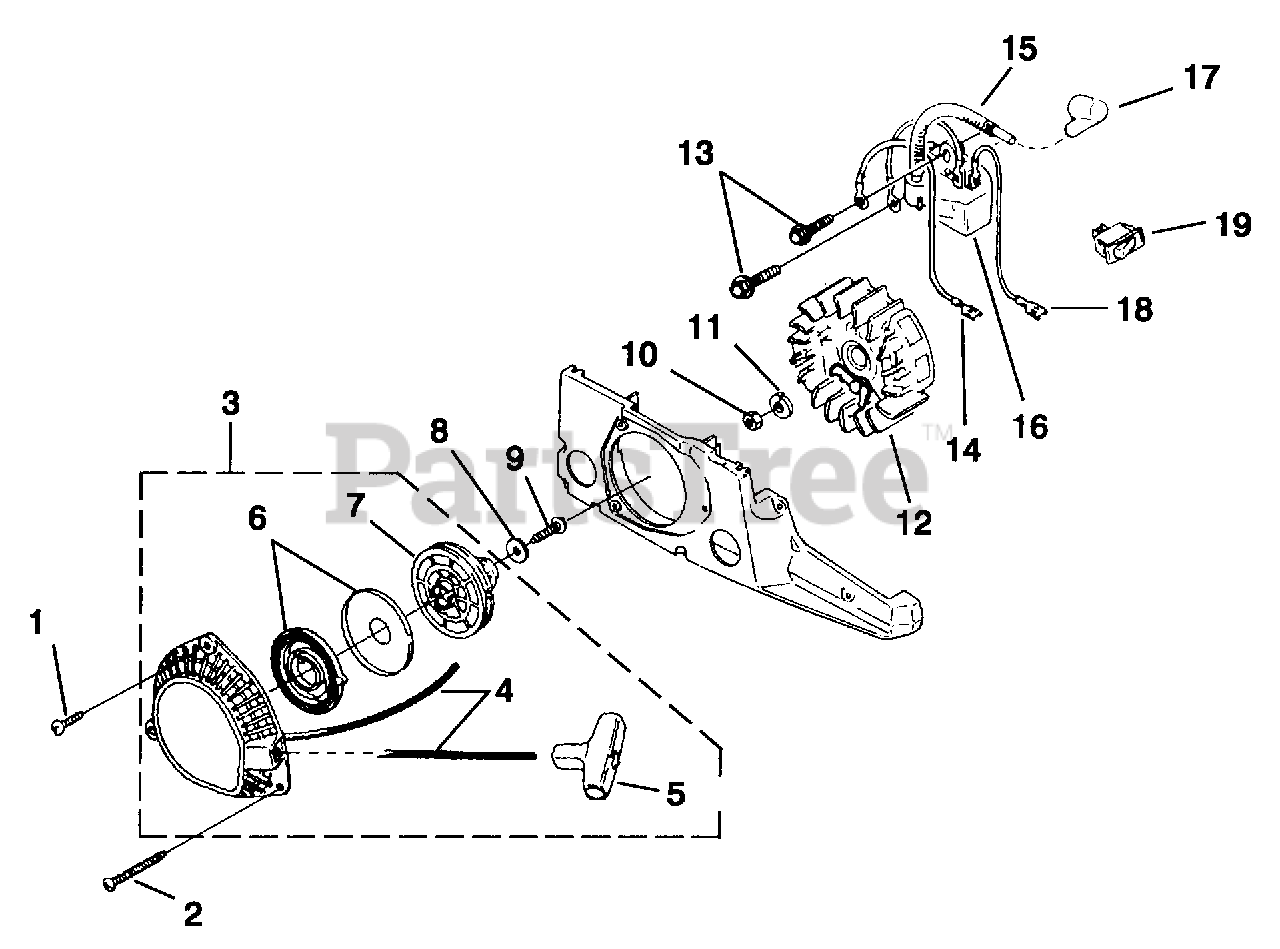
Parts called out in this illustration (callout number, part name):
1	SCREW-Thread Form (8-16 x 5/8")
2	SCREW Thread Form (8-16 x 2 1/4)
3	STARTER - COMPLETE
4	ROPE, STARTER (46")
5	GRIP, STARTER
6	SPRING & CONTAINER
7	PULLEY
9	SCREW Plastite (10-14 x 5/8")
10	NUT, JAM (3/8" X 24)
11	WASHER LOCK (3/8")
12	ROTOR & STARTER PAWLS
13	SCREW, Sems Hex Hd. (10-24 x 7/8")
14	IGNITION GROUND WIRE
15	SLEEVE, Insulating
16	IGNITION MADULE
17	SPARK PLUG BOOT KIT
18	IGNITION WIRE
19	SWITCH
